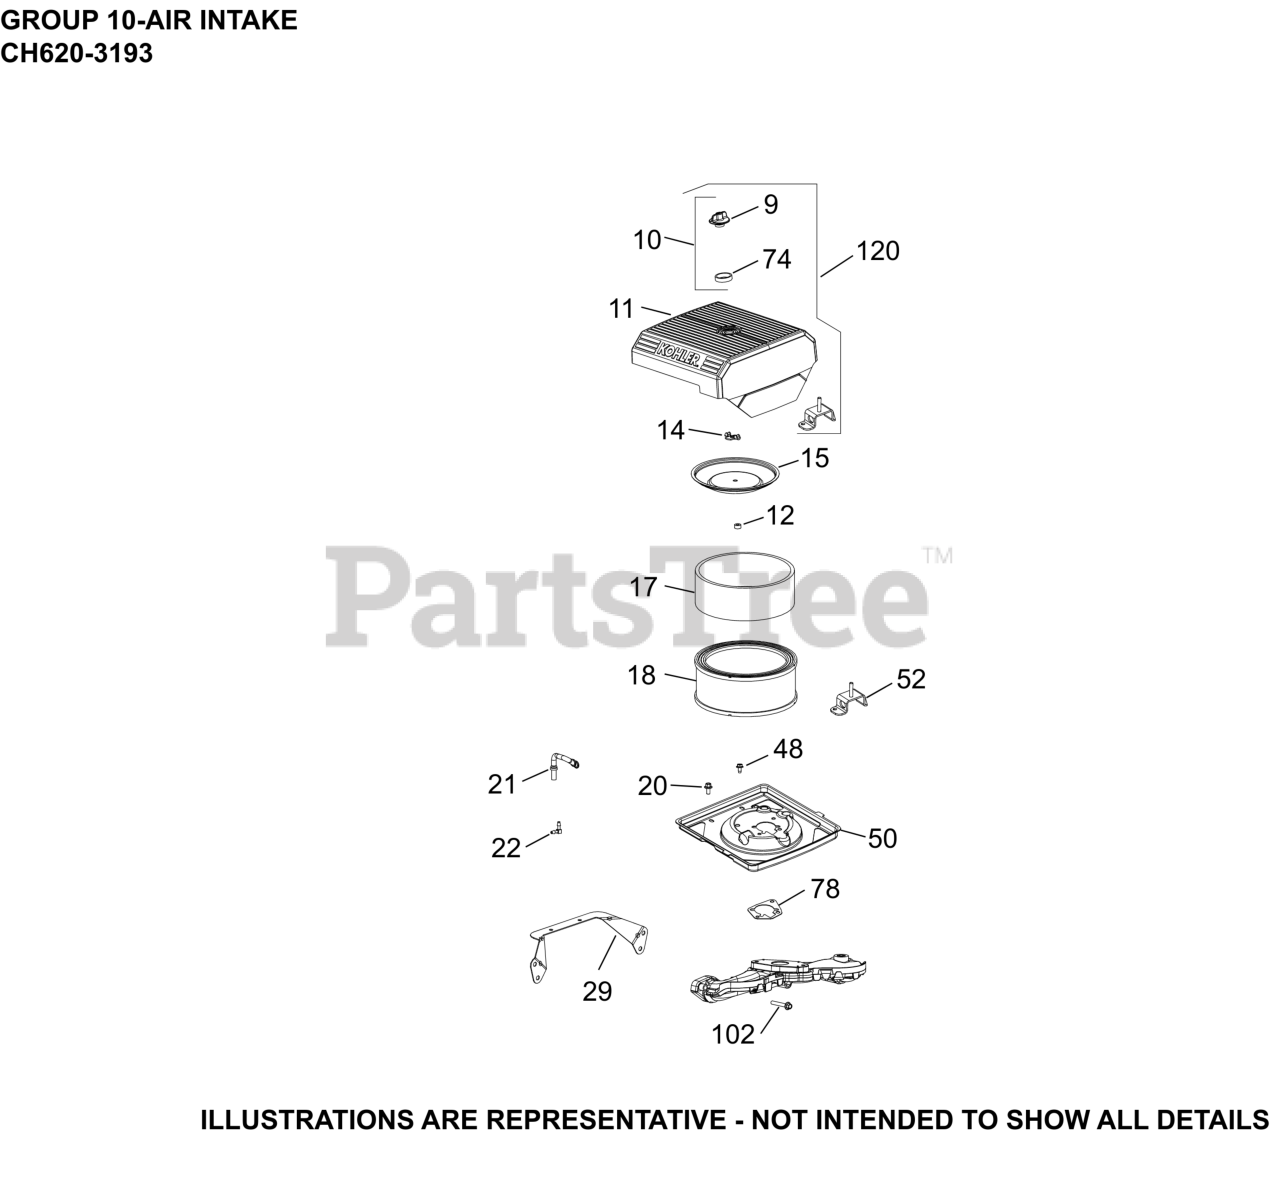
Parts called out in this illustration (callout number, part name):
9	KNOB, COVER
10	KIT, KNOB W/SEAL
11	COVER, AIR CLEANER
12	SEAL, INNER AIR CLEANER
14	NUT, WING
15	COVER, INNER AIR CLEANER
17	PRE CLEANER LOW ELEMENT
18	ELEMENT, AIR CLEANER
20	SCREW, FLG THD FRM M6X1.0X16
21	HOSE, EVAP
22	CONNECTOR, EVAPORATIVE HOSE
29	AIR CLEANER BRACKET
48	SCREW, THREAD FORMING
50	KIT, AIR CLEANER BASE
52	BRACKET, AIR CLEANER
78	GASKET, AIR CLEANER BASE
102	SCREW, FLG M6X1.0X40
120	KIT, AIR CLEANER COVER
